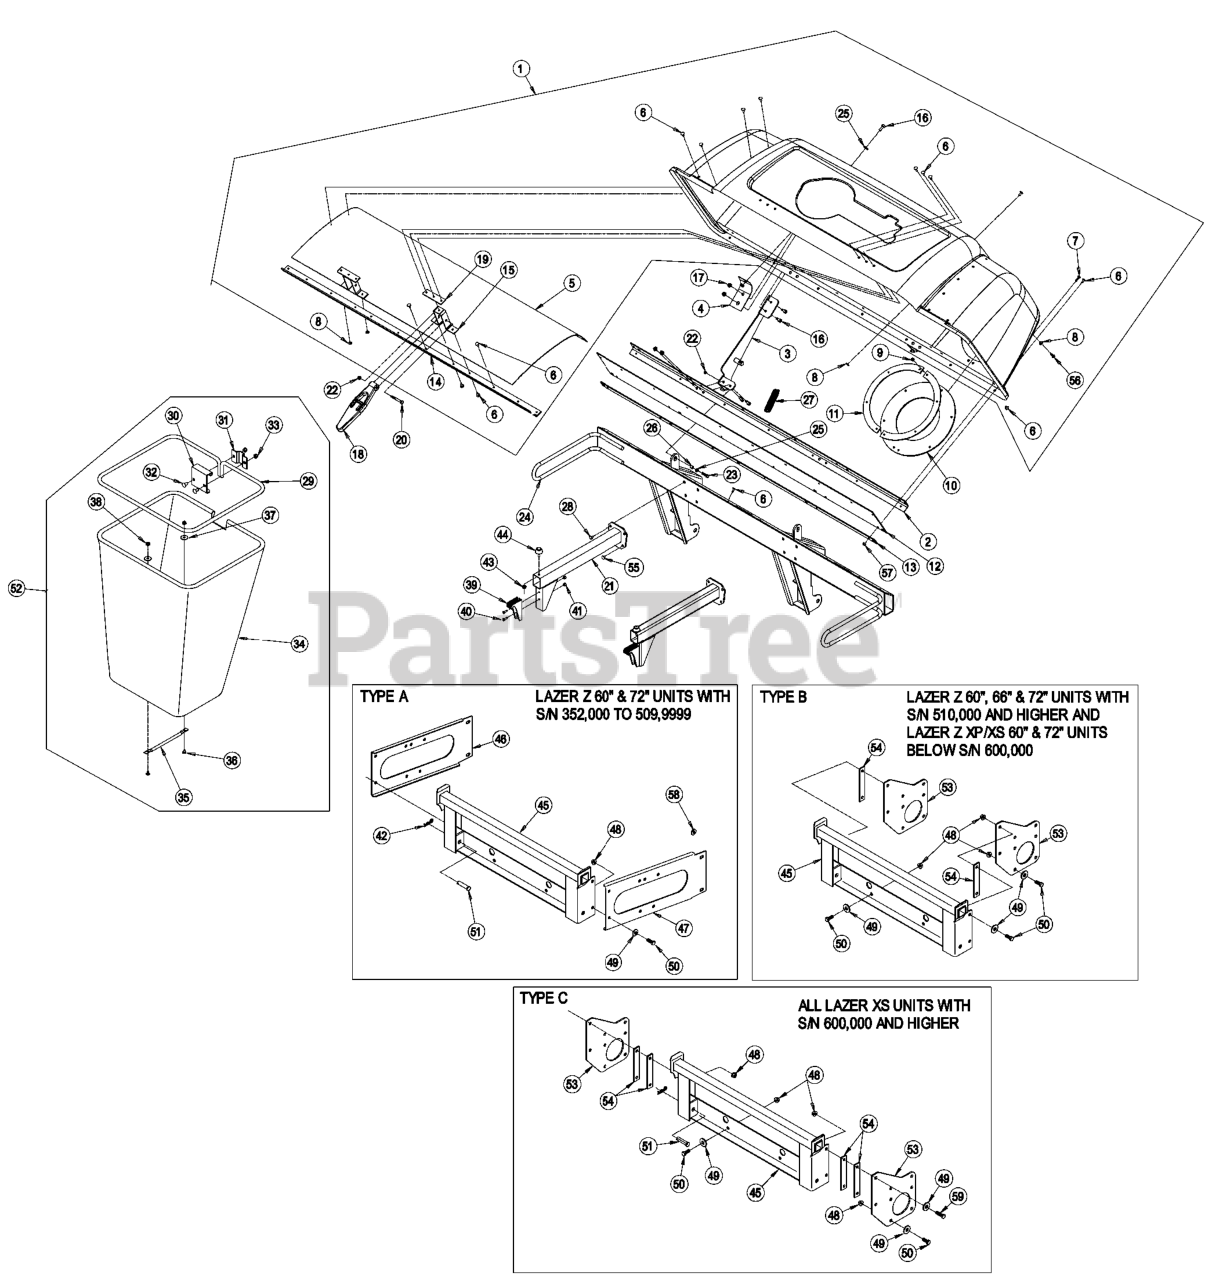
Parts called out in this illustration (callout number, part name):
1	ASM, HOOD
2	STIFFENER-BAGGER, TOP
3	HINGE ASM
4	REINFORCEMENT-HOOD, BAGGE
5	SCREEN-BAGGER
6	RIVET-BLIND
7	SCREW-HEAD, TRUSS
8	WASHER-FLAT
9	NUT-LOCK, NI
10	SEAL-TUBE
11	CLAMP-SEAL
12	SEAL-HINGE
13	PLATE-BACKING
14	SUPPORT-SCREEN
15	BRACKET-MOUNT
16	SCREW-HH
19	PLATE-LATCH, REINFORCEMEN
20	SCREW-HH
21	SUPPORT-BAG
22	NUT-LOCK, NI
23	SCREW-HH
24	UPRIGHT BAGGER ASM
25	WASHER-FLAT
27	SPRING-EXTENSION
28	SCREW-HH
29	FRAME-BAG
30	HANGER-BAG
32	BOLT-CARR
33	NUT-LOCK, NI
35	HANDLE-BAG
36	BOLT-CARR
38	NUT-LOCK, NI
40	SCREW-PPH
42	PIN-COTTER
45	MOUNT-BAGGER
46	BRACKET-FRAME, LH
47	BRACKET-FRAME, RH
48	NUT-HHF, WHIZ
49	WASHER-BELLEVILLE
50	SCREW-HH
51	PIN-CLEVIS
52	BAG AND FRAME ASM
53	PLATE-MOUNT, BAGGER
54	SPACER
55	SCREW-HSBH
56	SCREW-PPH
57	NUT-LOCK, SIDE
58	SPACER
59	SCREW-HH
